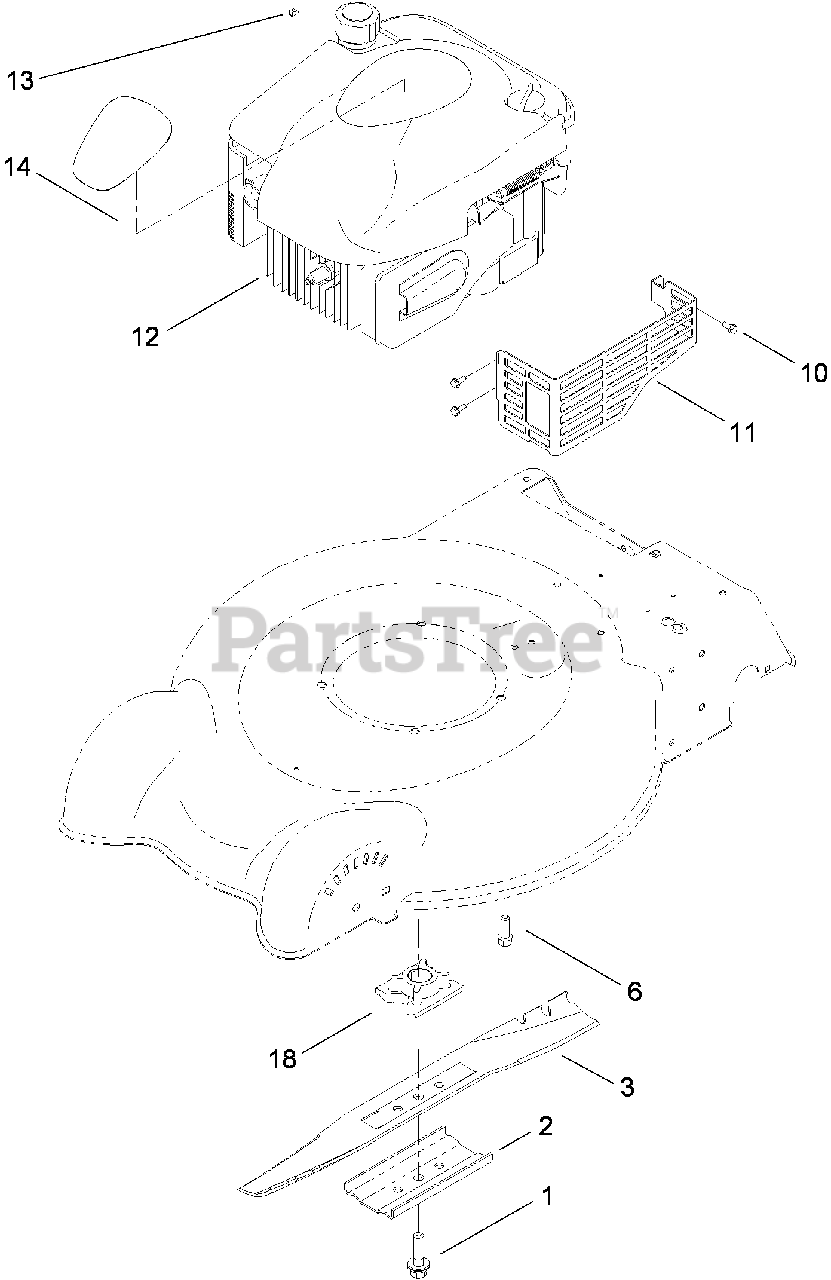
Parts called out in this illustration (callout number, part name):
1	BOLT-BLADE
2	SUPPORT-BLADE
3	BLADE-20 INCH
6	SCREW-TAPTITE
10	SCREW-TAPTITE
11	SHIELD-MUFFLER
13	STOP-ROPE
14	DECAL-SHROUD
18	RETAINER-BLADE
